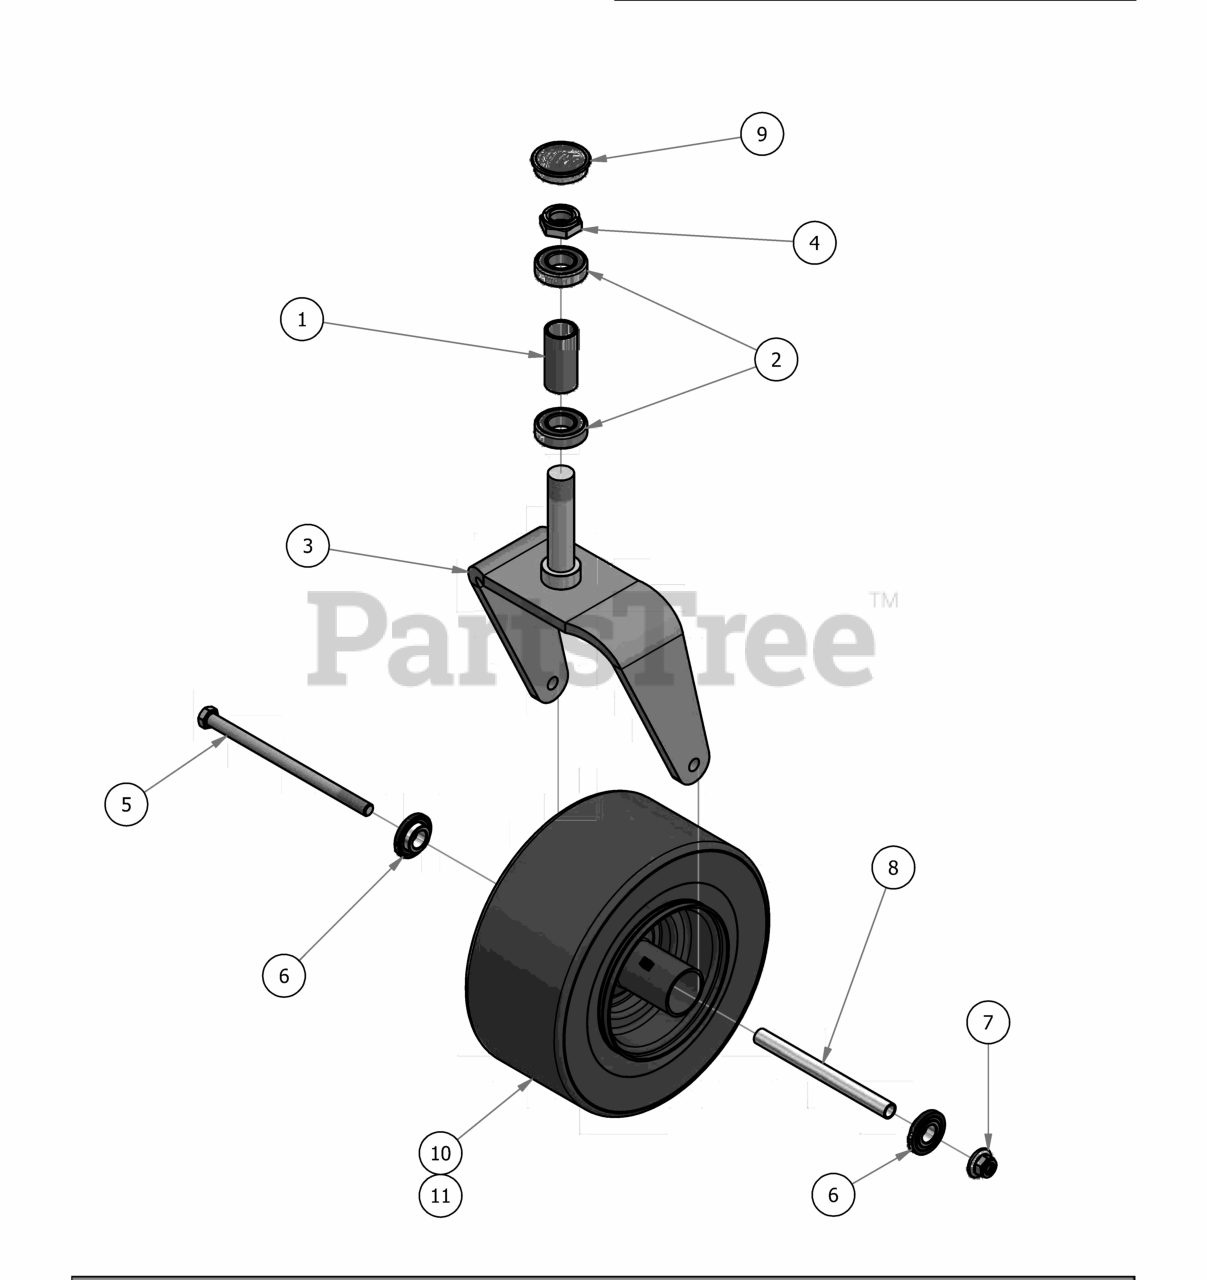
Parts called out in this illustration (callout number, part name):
1	2016 Front Bearing Spacer
2	Caster Bearing 2016 - 1641 Bearing
3	Front Fork
4	1" Fine Thread 1/2 Nylock Nut
5	1/2" x 9" GR 5 Hex Bolt
6	1 3/8" Wheel Bearing
7	1/2-13 Nylon Flange Nut
8	Front Wheel Spanner
9	2017 Bearing Cover
10	Tire and Wheel Assembly
11	Tire Only 13 x 6.50 - 6
